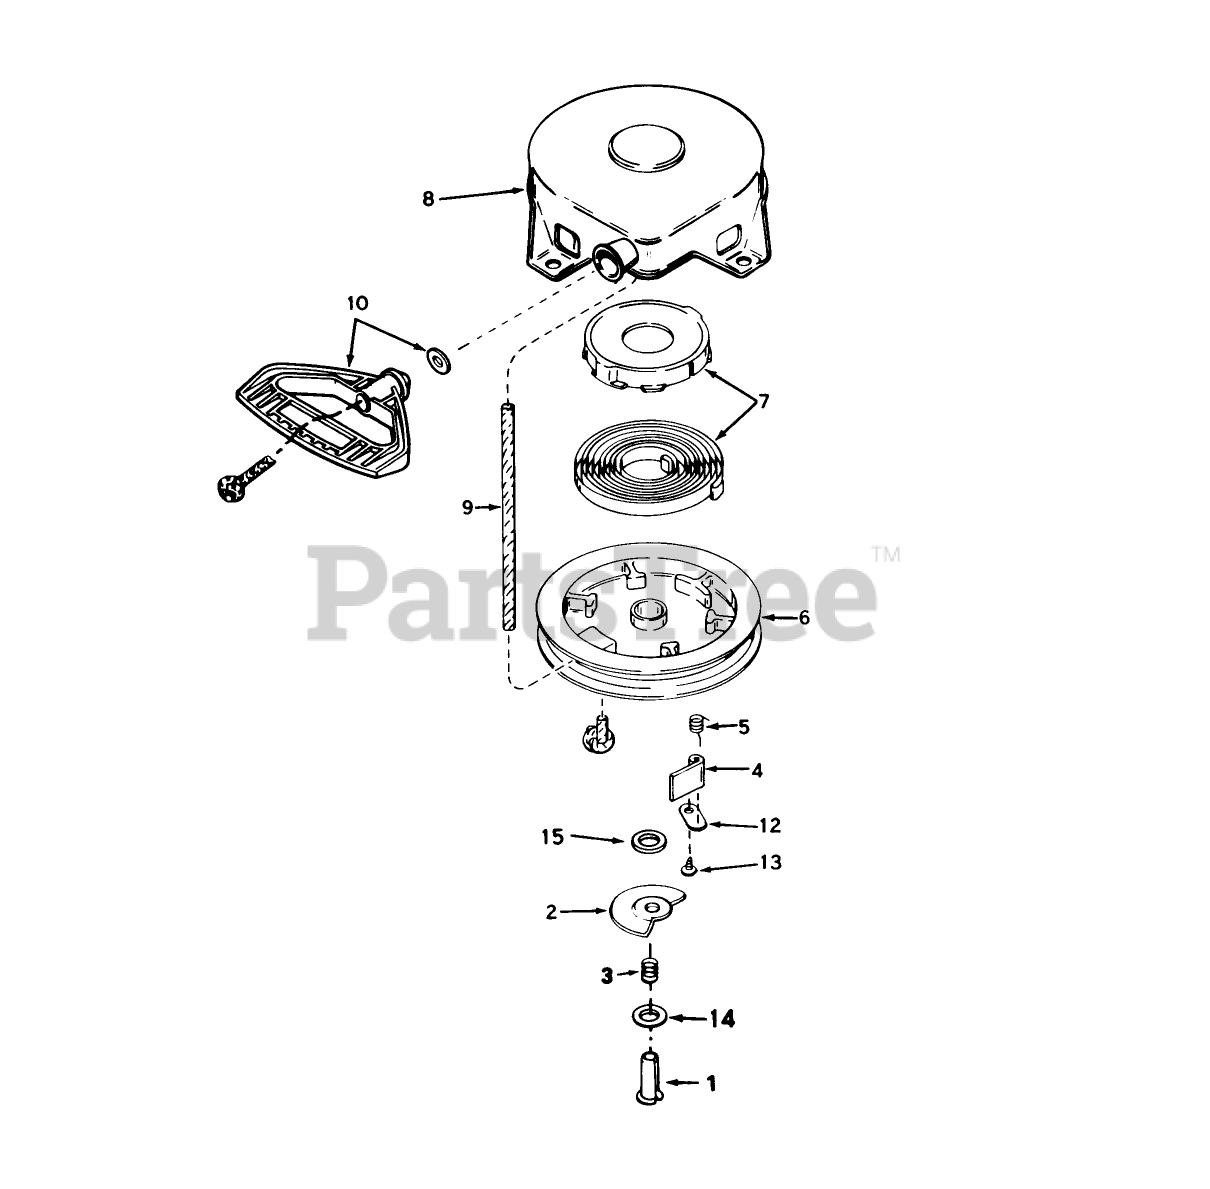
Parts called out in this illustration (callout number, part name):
1	Pin Spring
2	Washer
3	Brake Spring
4	Dog-Starter
5	Spring-Dog
6	Pulley
7	Spring Keeper Assy
8	Housing-Starter
9	Rope-Starter
10	Handle-Starter, Mitten Grip
12	Retainer-Dog
13	Screw
14	Washer
15	Washer
